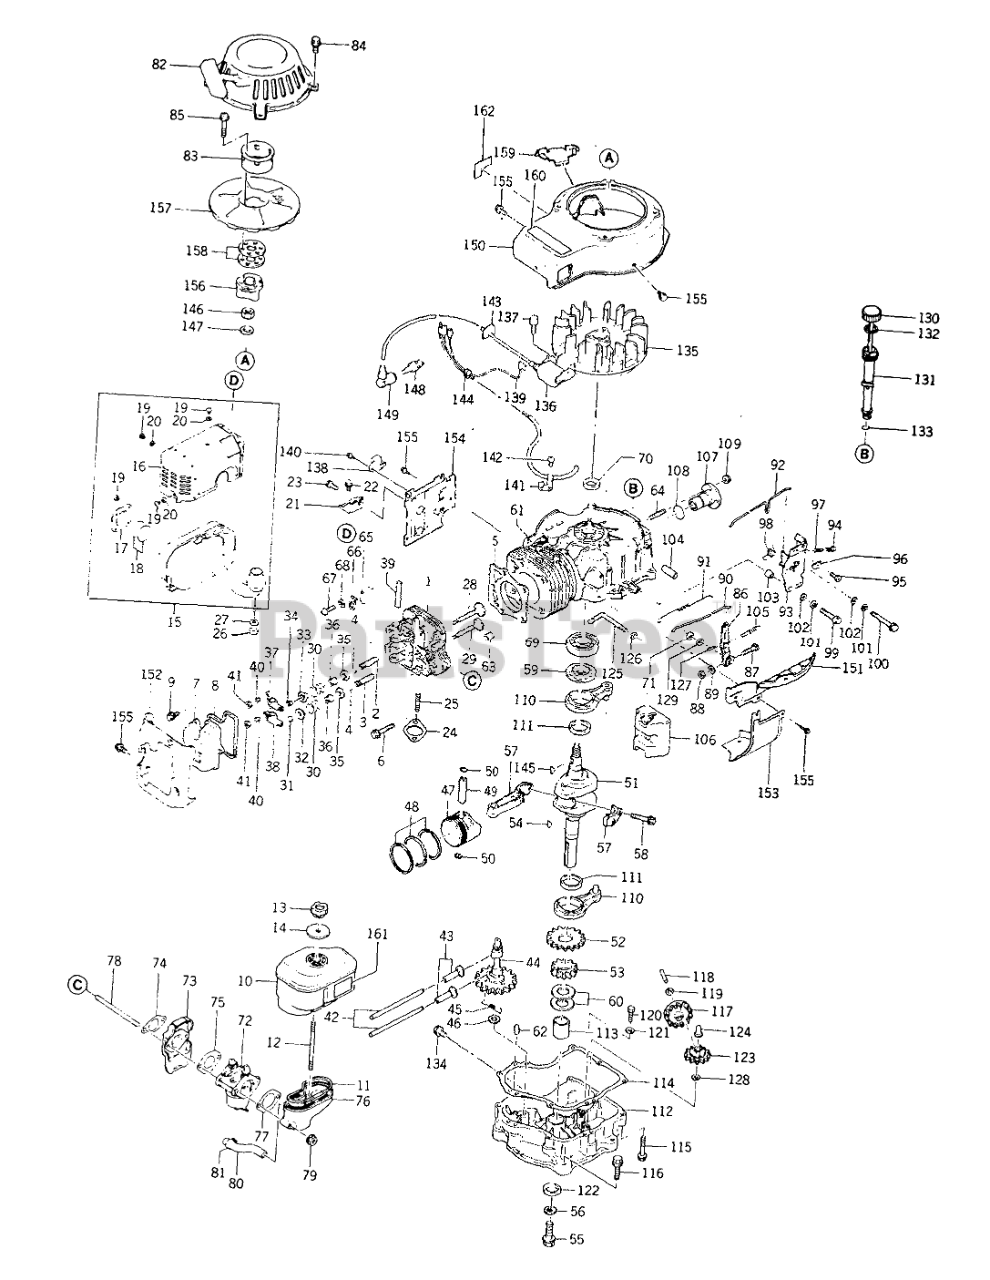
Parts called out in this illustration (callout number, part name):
1	CYLINDER HEAD COMP
2	GUIDE, valve (IN)
3	GUIDE, valve (EX)
4	RING, snap
5	GASKET, head
6	Bolt-Flanged
7	CASE, rocker
8	GASKET. rocker case
9	BOLT (6x14)
10	AIR FILTER ASSY
11	GASKET. air filter
12	STUD
15	MUFFLER ASSY
16	COVER, muffler
18	ARRESTER, spark
20	WASHER
21	BRACKET, muffler
22	BOLT (8x14)
23	BOLT (8x18)
25	STUD
26	NUT-HEX, SMALL (8mm)
27	Washer-Spring (8mm)
28	VALVE, intake
29	VALVE, exhaust
30	Spring-Valve, Engine
31	Cap-Valve
32	Retainer-Valve Spring
33	Retainer-Spring, Valve
35	Seat-Spring
36	SEAL, oil
37	ARM, rocker
38	Arm-Rocker
39	SHAFT, rocker
42	ROD, push
44	CAM SHAFT COMP
46	SHIM t=1.60
47	PISTON S.T.D.
48	Ring-Set, Piston
49	Pin-Piston
50	Ring-Snap
51	SHAFT, crank
52	GEAR, spur
53	GEAR, helical
57	CONNECTING ROD ASSY S.T.D.
58	Bolt
60	SHIM t=1.13
61	CRANK CASE COMP
62	Dowel Pin
68	WASHER
69	BEARING, ball (6306)
71	SEAL-OIL (VC6X10X2.6)
72	CARBURETOR ASSY
73	INSULATOR
74	GASKET
75	GASKET
76	PIPE, intake
77	GASKET
79	Nut
80	TUBE, breather
82	RECOIL STARTER ASSY
84	BOLT-FLANGED (6X10)
85	Bolt-Flanged (6X45)
87	Bolt (6X28)
88	NUT-HEX (6mm)
89	Washer-Plain (6mm)
90	LINK, governor
91	SPRING, link
92	LINK, choke
93	Control Panel Assy
95	Bolt
99	BOLT (6x30)
100	BOLT (6x55)
101	Lockwasher
106	WEIGHT COMP
109	Nut
110	ROD ASSY
111	BEARING, plain
112	CRANK CASE COVER COMP
113	BEARING, plane
115	Bolt-Flanged
116	Bolt-Flanged (8X25)
117	SLINGER, oil
120	BOLT (5x12)
122	SEAL, oil
123	GOVERNOR ASSY
124	Sleeve
125	ARM, pivot
126	Washer
127	Pin-Snap (1.2 X 21.2)
130	GAUGE, oil
132	Gasket
133	O-RING (16mm)
135	FLYWHEEL COMP
136	COAL, ignition
137	Bolt-Flange
138	Igniter
139	WIRE, lead
140	SCREW (4x8)
146	NUT (16mm)
148	PLUG, spark
149	Cap-Spark
150	HOUSING, fan
151	HOUSING, fan
155	Bolt-Flanged (6X12)
158	SHIM t=1.2
160	LABEL, brand
161	Decal-Engine Air Cleaner
162	LABEL, manual
